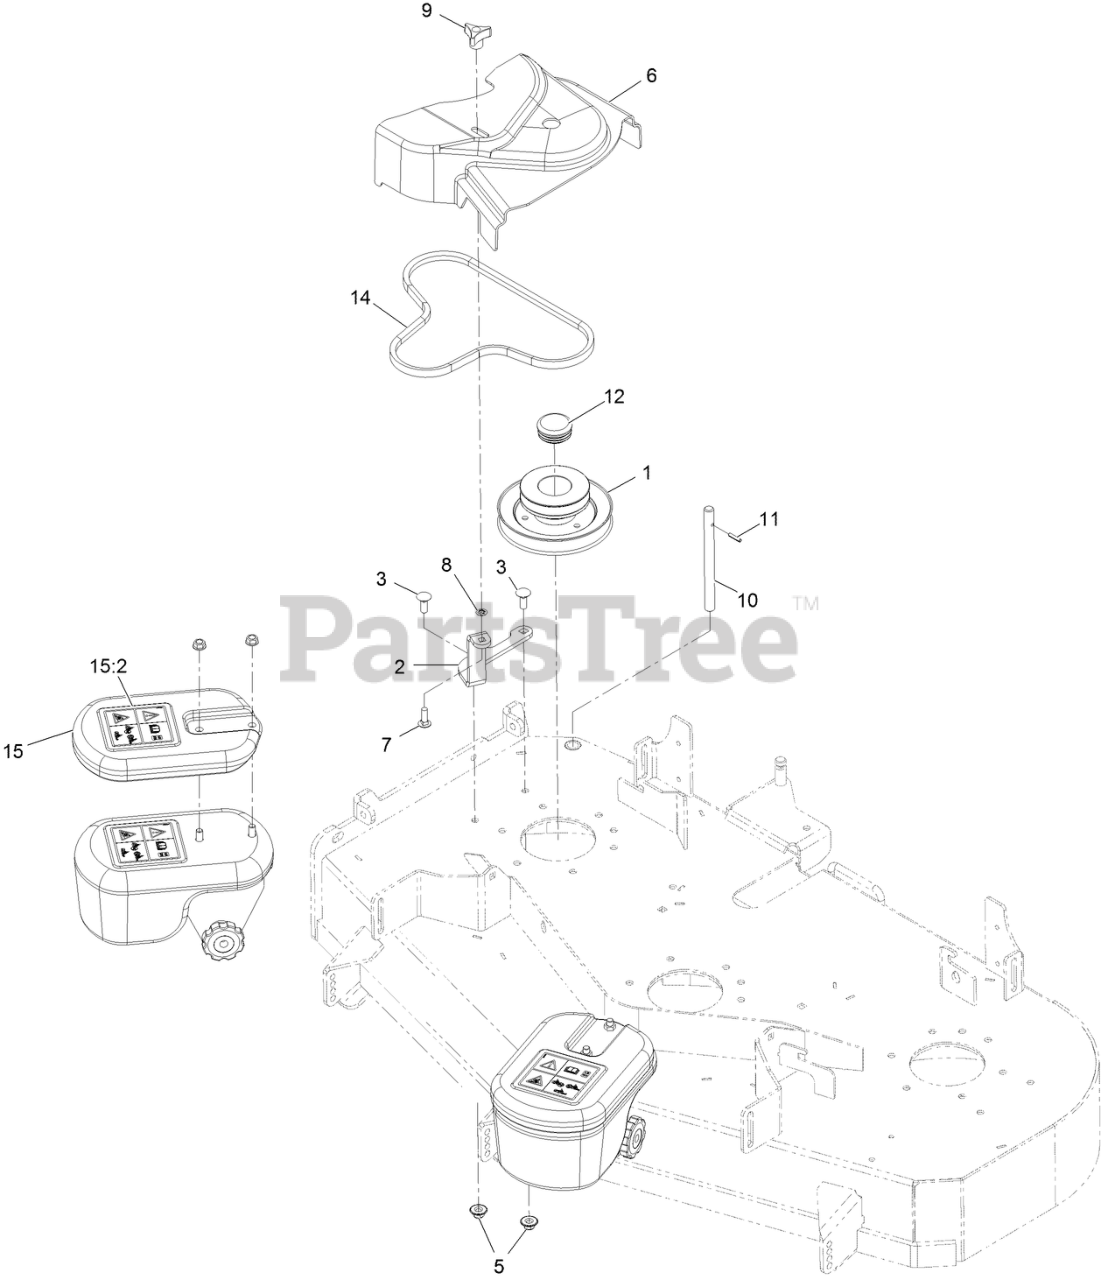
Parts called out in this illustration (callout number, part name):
1	JACKSHAFT-UV DRIVE, 484 SPLINED
2	BRACKET, SMALL UV BELT COVER
3	BOLT-CARR
5	Nut-Nyloc 3/8-16 Flg
6	COVER-BELT, UV 48
7	BOLT-CARR
8	RING-RETAINING, BOLT
9	KNOB-3 PRONG
10	SHAFT-CATCHER, GRASS
11	PIN-ROLL
12	PLUG-ROUND PLASTIC
14	BELT-BLOWER
15:2	DECAL-WARNING, TRACTION
